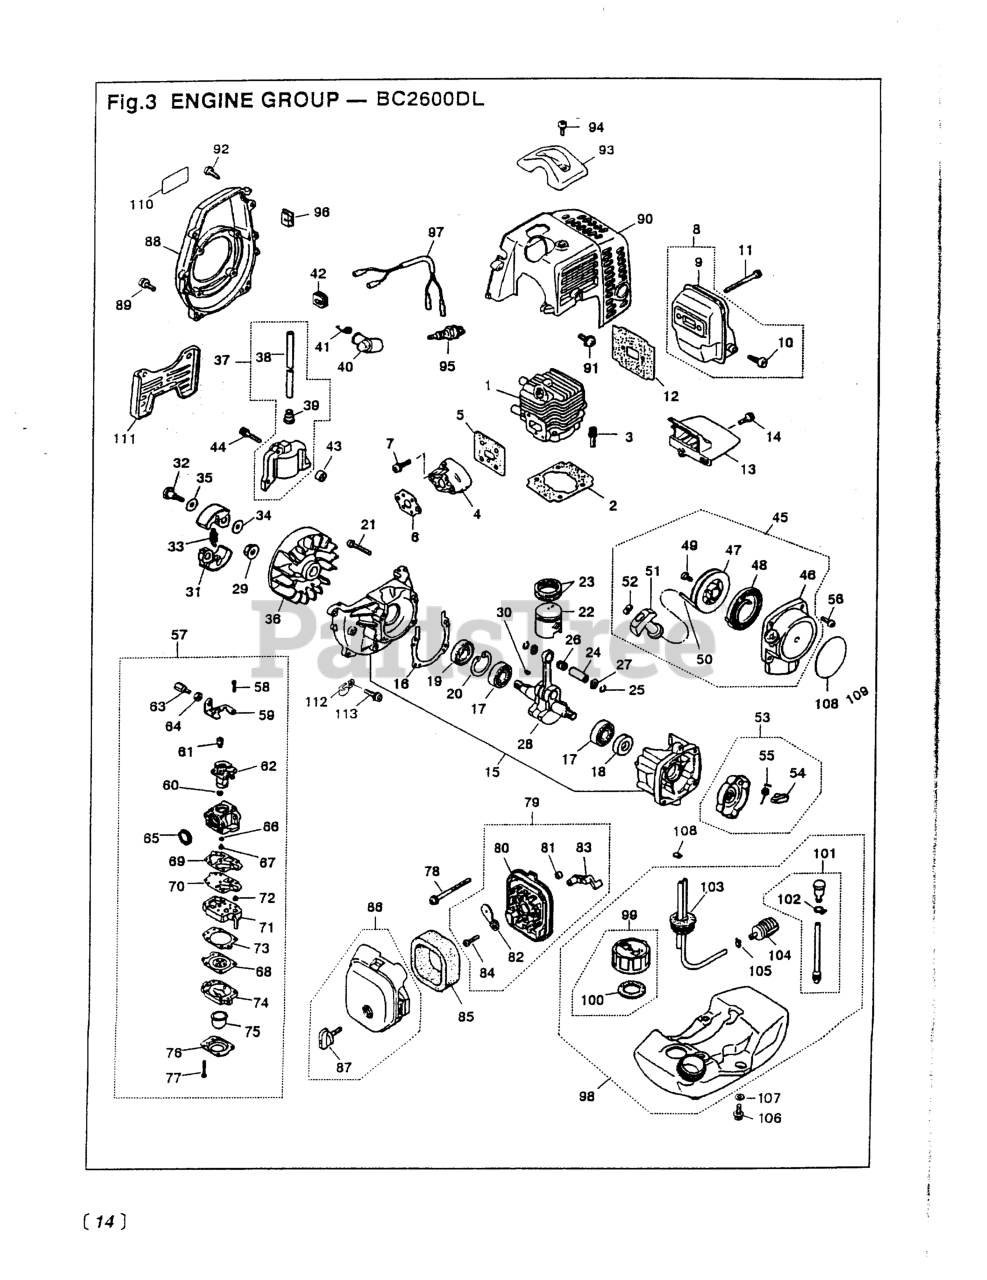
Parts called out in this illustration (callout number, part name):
1	CYLINDER
3	BOLT, M5 X 22
4	INSULATOR
7	SCREW, M5X20 (RPLS.1400-75510)
9	MUFFLER ASSY (USE 5913-15100)
10	ARRESTER (RPLS 5850-15140)
11	BOLT, M5 x 50
12	GASKET, MUFFLER
14	SCREW, M4 X 16
15	CRANKCASE
17	BEARING
18	SEAL, OIL (RPLS 1100-21210)
19	SEAL, OIL (RPLS 1140-21220)
20	RING, SNAP, M28 x 1.2
21	BOLT, M5 X 30
22	PISTON
23	RING, PISTON
24	PIN, PISTON
25	RING, SNAP (RPLS 1101-41320)
27	WASHER
28	CRANKSHAFT (RPLS 1850-42000)
30	KEY
32	BOLT
33	SPRING, CLUTCH (RPLS-51220)
34	WASHER, FLAT (USE 182303)
38	CORD
39	CAP
41	SPRING
42	GROMMET
44	BOLT
45	RECOIL ASSEMBLY
46	CASE
47	REEL
48	SPRING, SPIRAL
49	SCREW (RPLS -75150)
51	KNOB
52	PLATE, STOPPER
53	PULLEY ASSY (RPLS -75210)
54	RATCHET (RPLS 1850-75220)
55	SPRING, RETURN
56	SCREW, M4 X 16
57	CARBURETOR (WYJ-117)
58	SCREW
60	RING
61	SWIVEL
62	VALVE ASSY
63	SCREW, CABLE ADJUSTER
64	NUT, CABLE ADJUSTER
65	RING, PACKING
66	RING, O
68	DIAPHRAGM (USE 4810-81260)
69	GASKET, PUMP
70	DIAPHRAGM
71	BODY, PUMP
73	GASKET, DIAPHRAGM
74	BODY, PURGE
75	PUMP, PRIMING
76	COVER, PUMP
77	SCREW
78	SCREW, M5 X 55
80	BODY
81	SLEEVE
82	PLATE, CHOKE (RPLS-82130)
83	LEVER, CHOKE
84	SCREW (REPLACES 50030272)
85	ELEMENT
89	SCREW, M5X20 (RPLS.1400-75510)
91	SCREW, M5 x 12
92	SCREW, HOUSING
93	GUARD, PLUG
94	SCREW,M5 X 14 (RPLS 1400-15510
97	CORD COMP (RPLS -73200)
99	CAP (RPLS -85200)
100	PACKING
102	CLIP
103	PIPE COMPLETE
104	FILTER ASSY
105	CLIP (REPLACES 2841-31280)
106	SCREW
107	WASHER
108	CLIP
110	LABEL, FAN COVER
112	CLAMP
113	SCREW,M5 X 14 (RPLS 1400-15510
